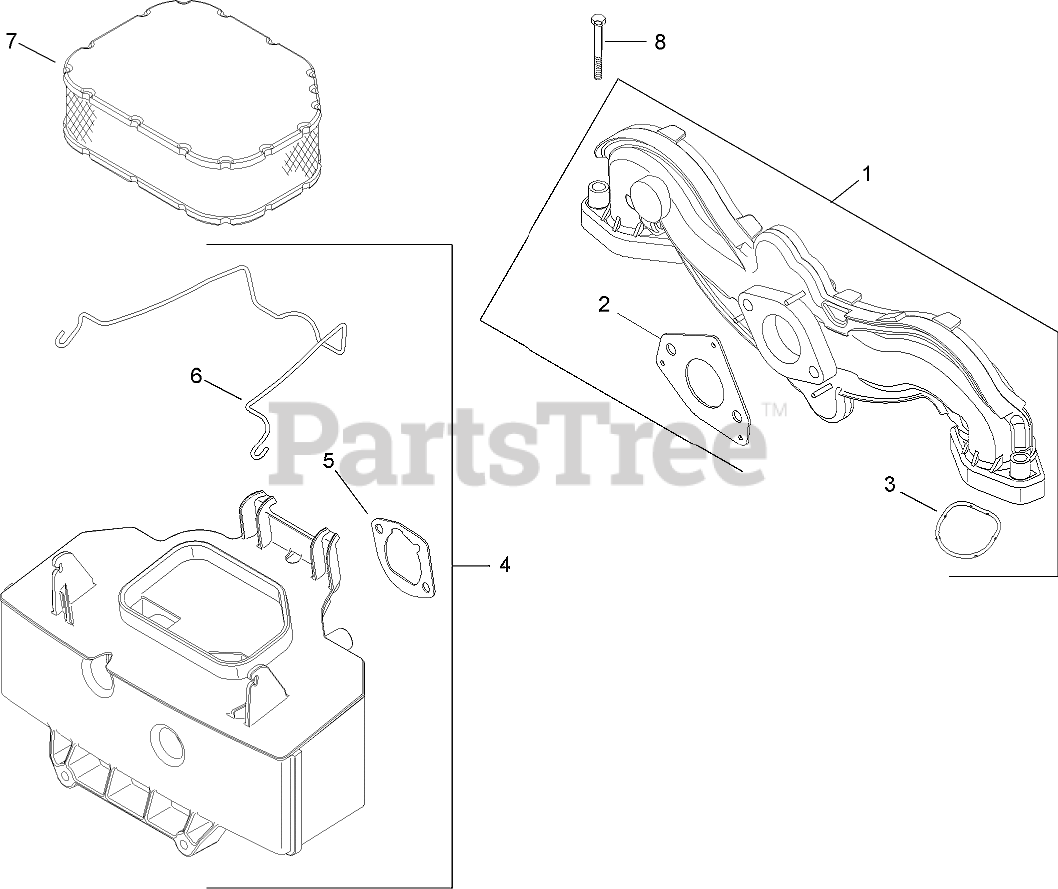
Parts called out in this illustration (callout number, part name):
1	Manifold-Intake
2	GASKET-CARBURETOR
3	O-RING
4	Base-Air Cleaner
5	GASKET-BASE, AIR CLEANER
6	LATCH-ELEMENT, AIR CLEANER
7	Element-Air Cleaner
8	SCREW-FLANGE (M6X1.0X40)
